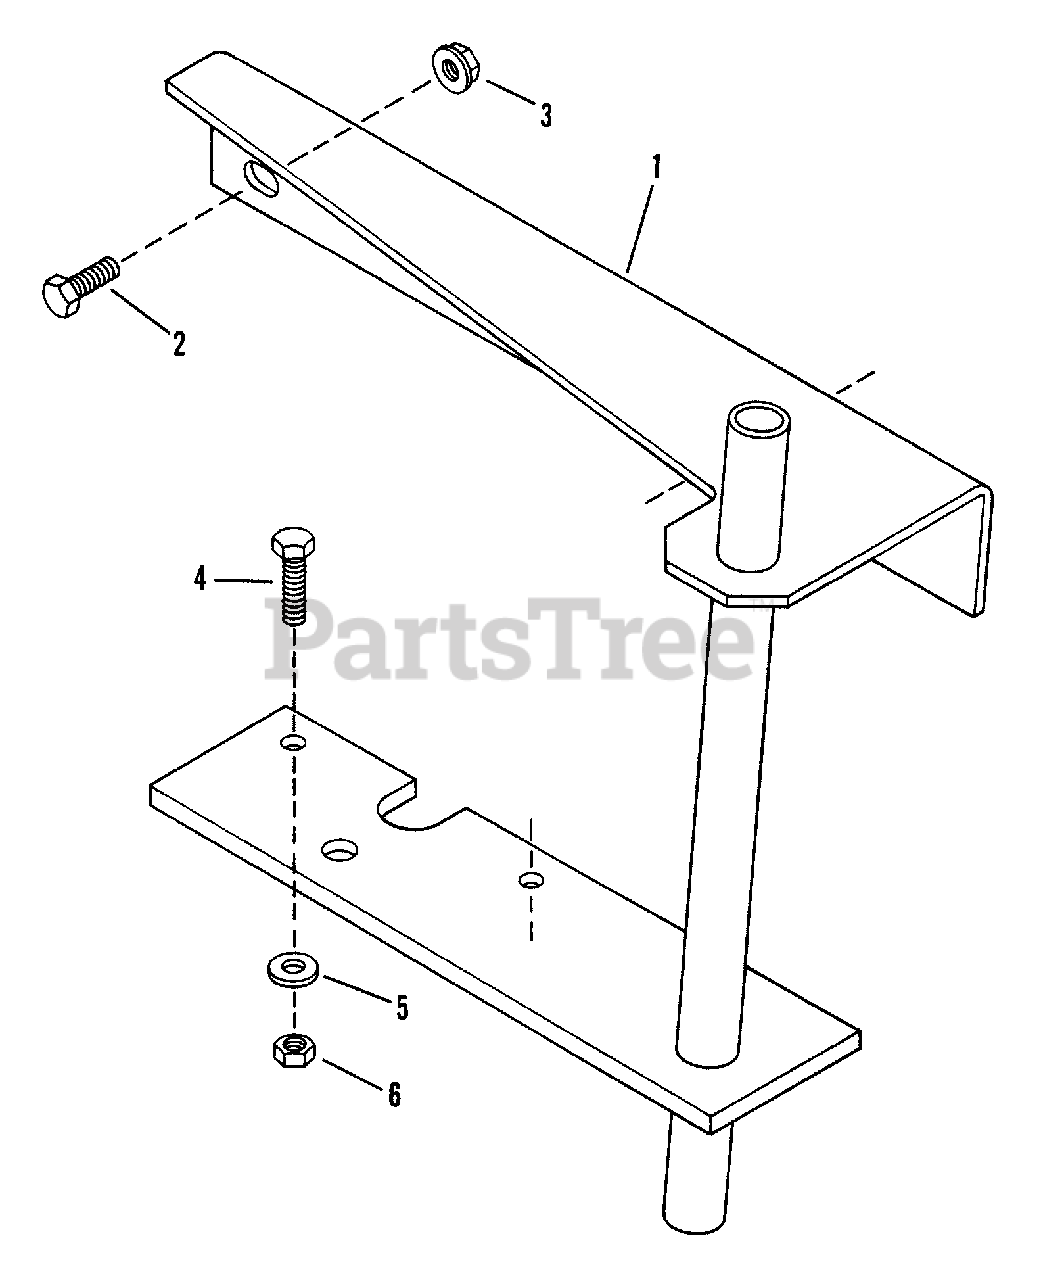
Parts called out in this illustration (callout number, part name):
1	STRUCTURE, Adapter
2	SCREW, 5/16-18x3/4" Hex Cap
3	NUT, 5/16-18 Hex Flange Lock
4	SCREW, 5/16-18x1" Hex Cap
5	WASHER, 5/16 Split Lock
6	NUT, 5/16-18 Hex
